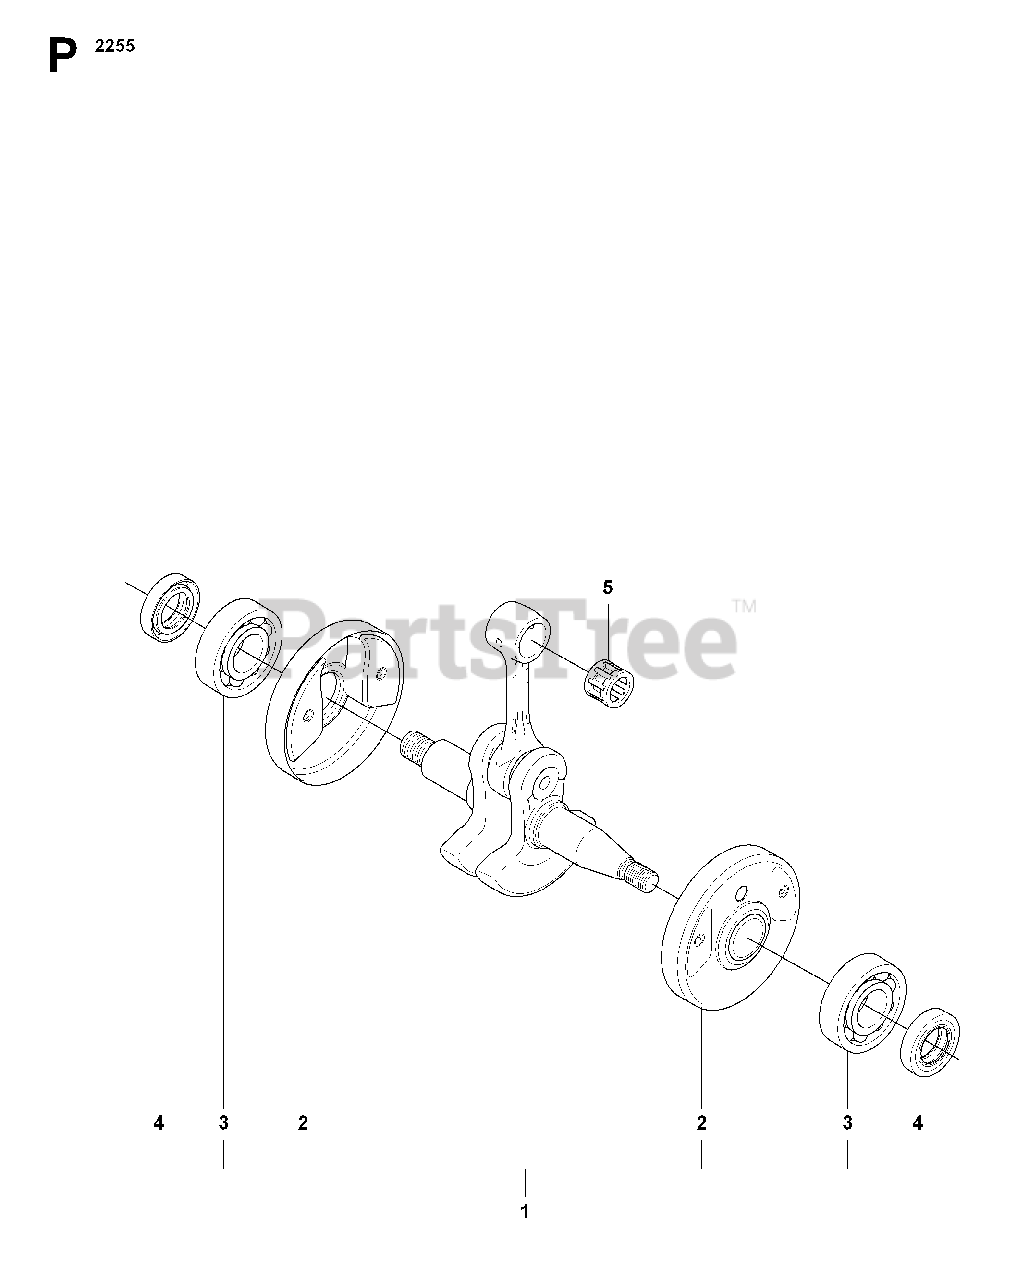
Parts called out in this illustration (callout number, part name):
1	CRANKSHAFT
3	BALL BEARING-6202-C3 SKF
4	SEALING RING
5	RP SUPPORT BUSHING
